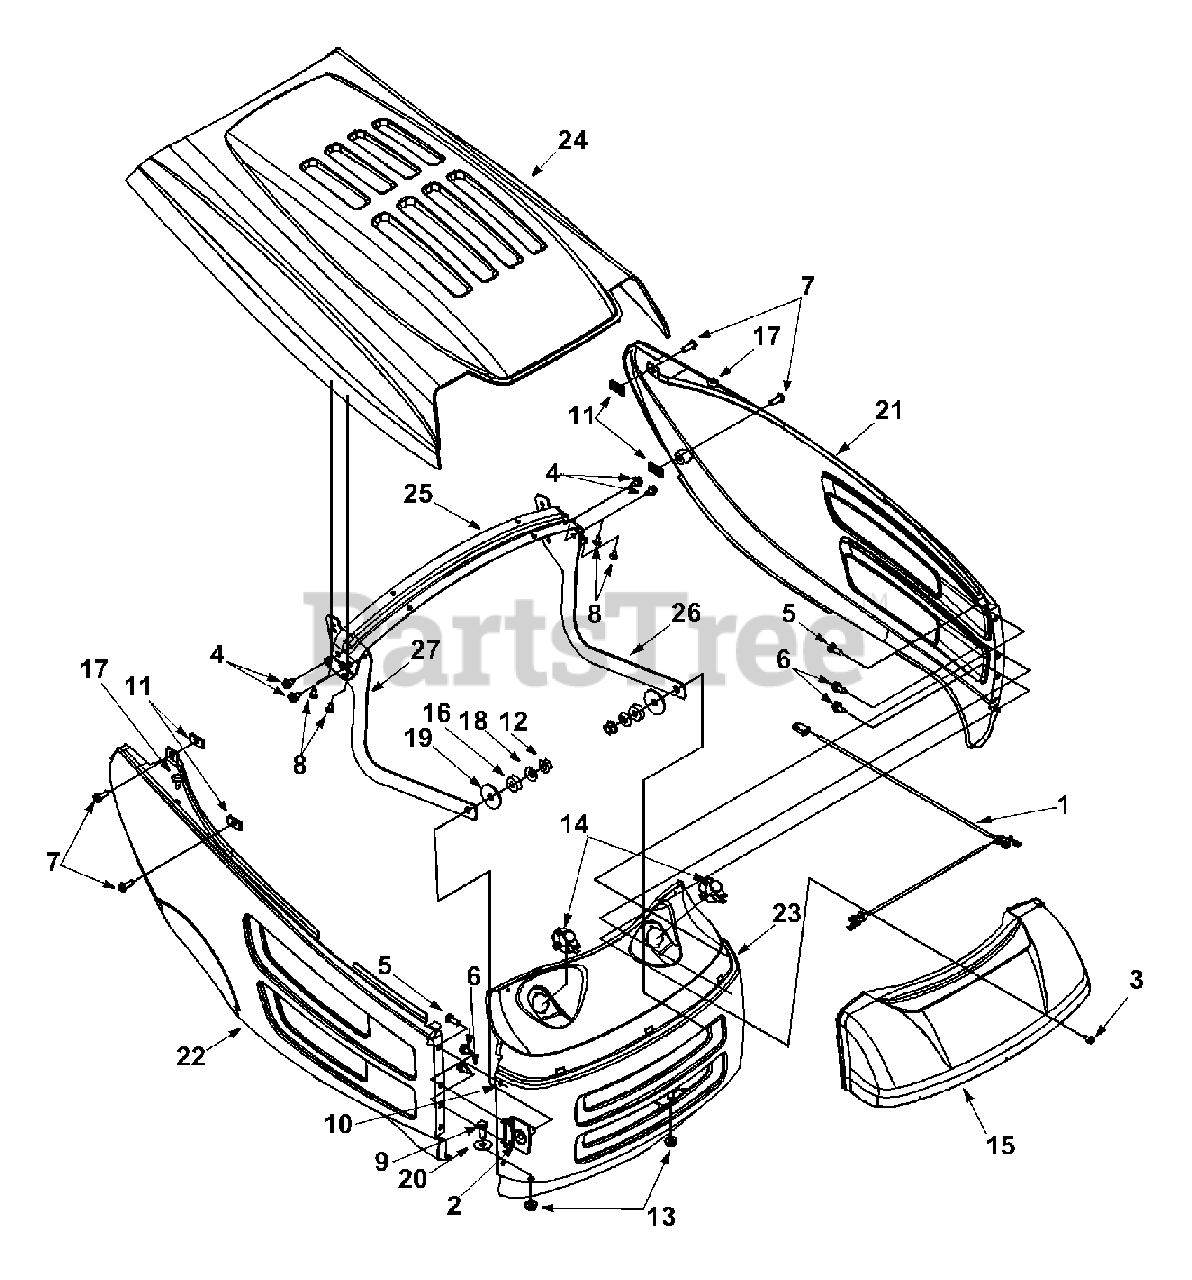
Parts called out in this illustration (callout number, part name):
1	Harness Assembly
3	Hex Wash. Tap Screw #10-16 Thd.
4	Hex Wash. TT-Tap Scr. 1/4-20 Lg.
5	Hex Bolt 1/4-20 x .62" Lg.
6	Hex Wash. Scr. 1/4-14 x .625" Lg.
7	Pan Hd. Mach. Scr. 1/4-20 x .75" Lg.
8	Torx Scr. #10-16 x .5" Lg.
9	Hex Bolt 5/16-18 x .75" Lg.
10	Hex Nut 1/4-20 Thd.
11	Tinn Nut 1/4-20 Thd.
12	Flange L-Nut 3/8-16 Thd.
13	Flange L-Nut 5/16-18 Thd.
14	Socket
15	Lens
16	Rubber Wash.
17	Rubber Bumper
18	Bell-Wash. .375" I.D. x .870" O.D.
19	Fl-Wash. .406" I.D. x 1.5" O.D.
20	Fl-Wash. .349" I.D. x 1.0" O.D.
